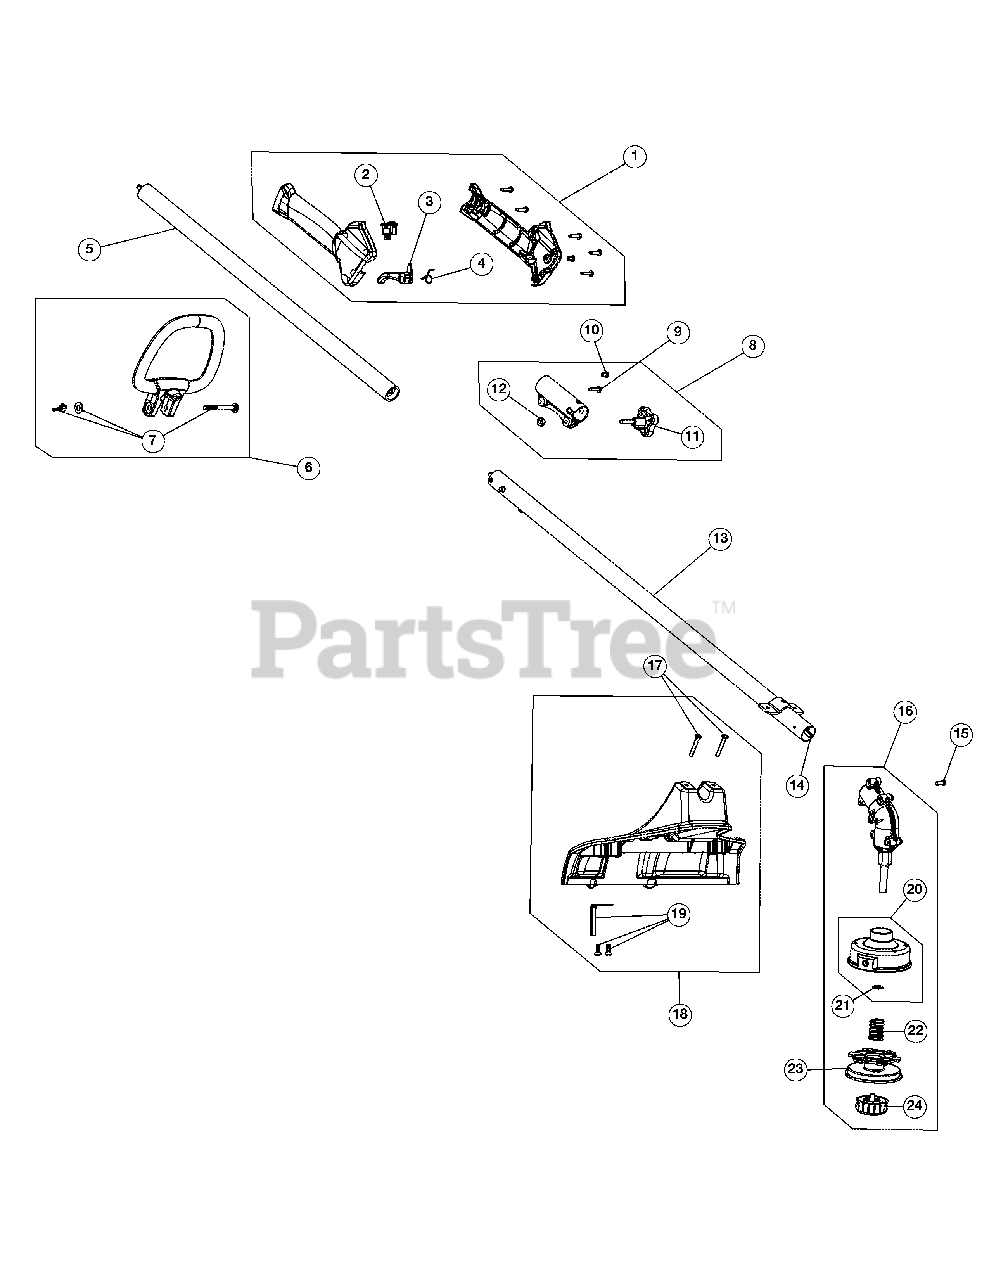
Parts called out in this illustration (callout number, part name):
1	Throttle Housing Assembly (Incl. 2-4)
3	Throttle Trigger
4	Throttle Trigger Spring
5	Upper Shaft Housing Assembly
6	D-Handle (Incl. 7)
7	D-Handle Hardware
8	Split Boom Coupler (Incl. 9-12)
9	Anti-Rotation Screw
11	Adjustment Knob
12	Knob Retainer Nut
13	Lower Shaft Housing Assembly
14	Lower Flexible Drive Shaft
15	Anti-Rotation Screw
16	Gearbox Assembly (Incl. 20-24)
17	Shield Mounting Screws
18	Shield Assembly (Incl. 17 & 19)
19	Blade Assembly
20	Outer Spool Assembly (Incl. 21)
21	Retainer
23	Inner Reel
24	Bump Head Knob Assembly
